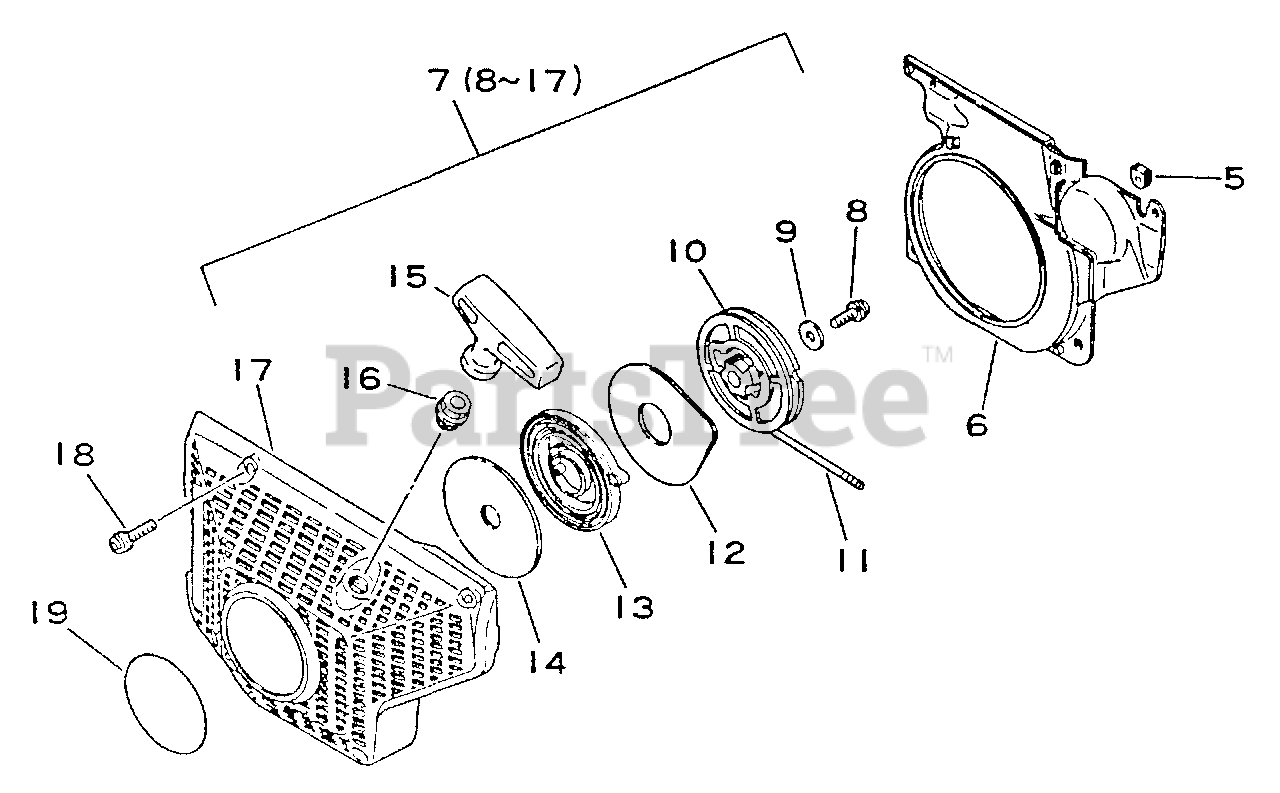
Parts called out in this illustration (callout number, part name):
6	SHIELD, FAN
7	STARTER ASSY
8	SCREW - 5×14
9	WASHER 5.5×12×0.8
10	REEL, ROPE
11	ROPE, STARTER
12	PLATE, SIDE
13	SPRING, RECOIL
14	PLATE, SIDE
15	GRIP, STARTER
16	GUIDE, ROPE
17	CASE, STARTER
18	SCREW - 5×20
19	LABEL - ECHO
